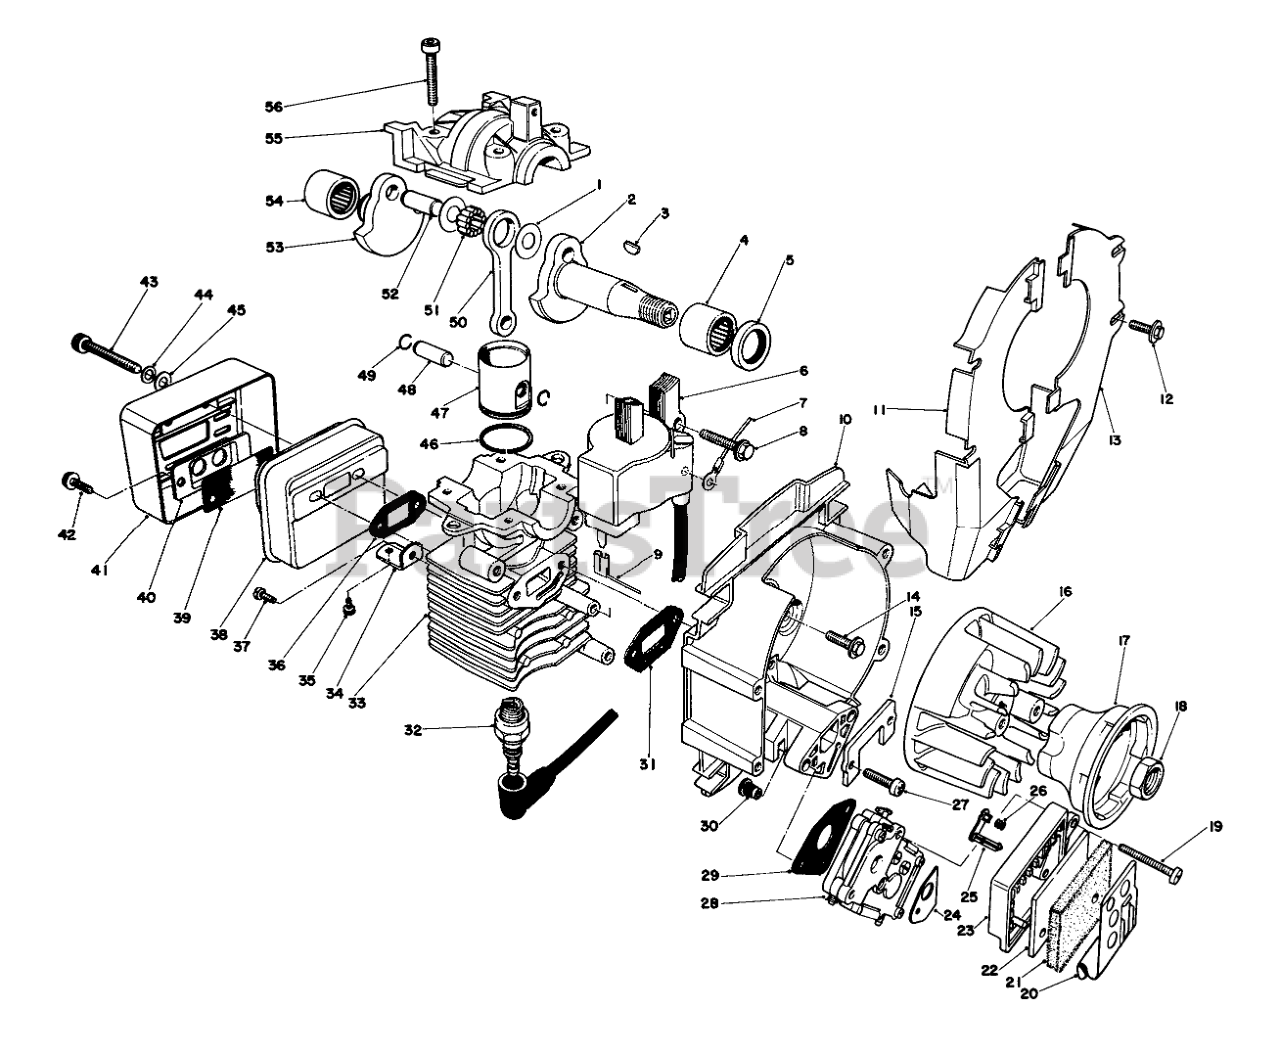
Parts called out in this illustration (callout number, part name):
2	Crankshaft & Connecting Rod Assembly (Incl. Ref. #1-2 & 50-53)
3	FLYWHEEL KEY
4	Main Bearing-Open End
5	Seal-Main Bearing
6	CDI Module
7	Wire-Ground/Switch
8	Screw CDI
9	Wire-Coil/Switch
10	Backing Plate
11	Cooling Shroud-Left Hand
12	Screw-Shroud
13	Cooling Shroud-Right Hand
14	Screw
15	Plate-Stress
16	FIywheel
17	Cup-Starter
18	NUT-JAM
19	Screw-Carburetor
20	Cover Air Cleaner
21	Foam Air Cleaner
22	Felt Air Cleaner
23	Spit Back & Choke Assembly (Incl. Ref. #24-26)
24	Choke Base Plate
25	Choke Lever
26	Spring
27	Screw, Intake
28	Carburetor Replacement Kit (Incl. Ref. #30)
29	Gasket-Carburetor
30	Insert Threaded
31	Gasket-Intake
32	SPARK PLUG (NGK)
33	Cylinder Assembly Kit (Incl. Ref. #31, 36 & 55-56)
34	Tab Shield
35	Screw-Heat Shield
36	Gasket-Exhaust
37	Screw Shield Tab
38	Muffler Kit (Incl. Ref. #3940 & 42)
39	Spark Arrestor
40	MUFFLER OUTLET PLATE
41	MUFFLER SHIELD
42	Screw
43	MUFFLER SCREW
44	WASHER-LOCK
45	WASHER-FLAT
46	Piston Ring
47	Piston Assembly (Incl. Ref. #48)
48	Piston Pin
50	Connecting Rod
51	Rollers-Crank Pin
52	Crankpin
53	Crankside-Stud
54	Main Bearing-Closed End
55	Crank Case
56	Screw-Cylinder & Crankcase
